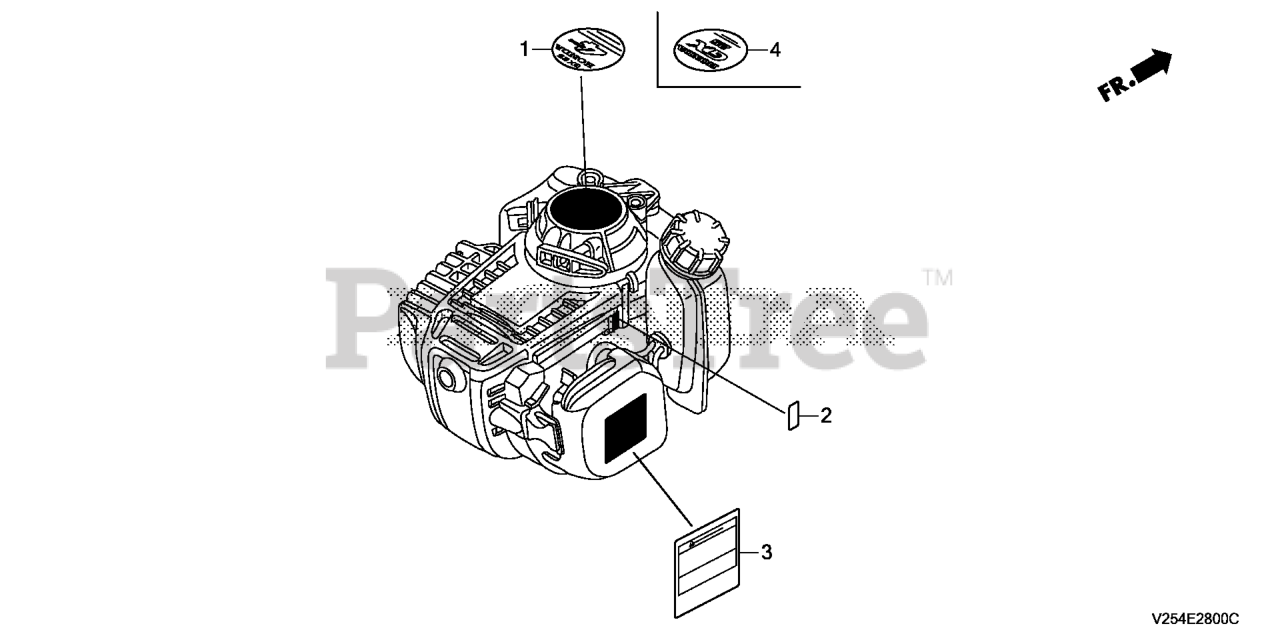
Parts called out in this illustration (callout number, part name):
2	MARK, TYPE (FY4)
3	MARK, OPER CAUTION
4	MARK, EMBLEM
